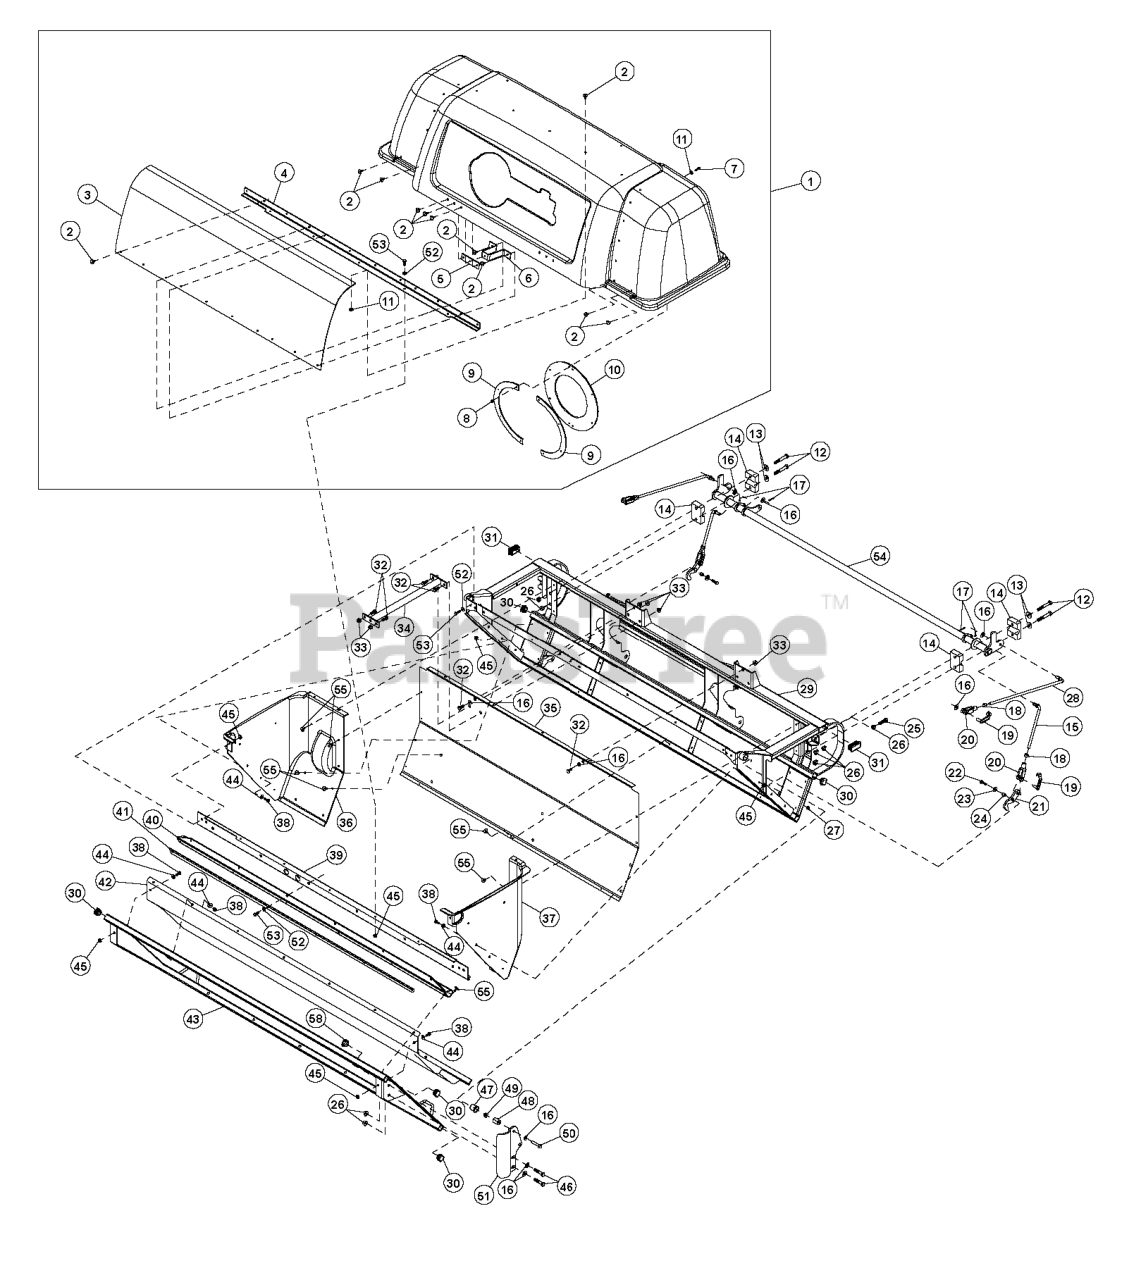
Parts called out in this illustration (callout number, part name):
1	Asm, Hood Dump
2	Rivet, Pop 3/16 x 1/2
3	Screen, Bagger
4	Support, Screen
5	Plate, Latch Reinforce
6	Bracket, Mount
7	Screw, #10-24 x 3/4 CRTH
8	Nut, Nyloc #10-24
9	Clamp, Seal
10	Seal, Tube
11	Washer, Flat .216 x .750
12	Screw, HH 3/8-16 x 2 1/2
13	Washer, Flat 7/16 x 2
14	Bearing, Block Half
15	Linkage, Handle
16	Washer, Flat .406 x .813
17	Pin, Cotter 1/8 x 3/4
18	Nut, HH 3/8-24
19	Pin, Spring Clevis 3/8
20	Yoke, Brake Linkage
22	Screw, HH 1/4-20 x 1
23	Washer, Flat 1/4
24	Spacer, Gommet
25	Bolt, Tap 3/8-16 x 1 3/4
26	Nut, HHF 3/8-16
27	Nut, Nyloc 1/4-20
28	Link, Hinge
29	Wld, Upright
30	Cap, Tube 1 x 1
31	Cap, Tube 1 x 2
32	Screw, HH 5/16-18 x 3/4
33	Nut, Whizlock 5/16-18
34	Wld, Rear Crossmember
35	Sheet, Wall
36	Panel, Bagger LH
37	Panel, Bagger RH
38	Screw, HH 1/4-20 x 5/8
39	Asm, Rear Crossmember
40	Seal, Door Hinge
41	Strap, Hold Down
42	Asm, Bag & Bottom Panel
43	Asm, Door Frame
44	Washer, Flat .312 x .750
45	Nut, Whizlock 1/4-20
46	Screw, HH 3/8-16 x 1
47	Bushing
48	Pin, Hinge Pivot
49	Nut-Nyloc 3/8-16
50	Screw, HH 5/16-18 x 1 3/4
51	Arm, Hinge LH
52	Washer, 1/4 SAE
53	Screw, HH 1/4-20 x 3/4
54	Wld, Intermediate Link
55	Rivet, Pop 3/16 x 1/2
58	Dome, Plug
